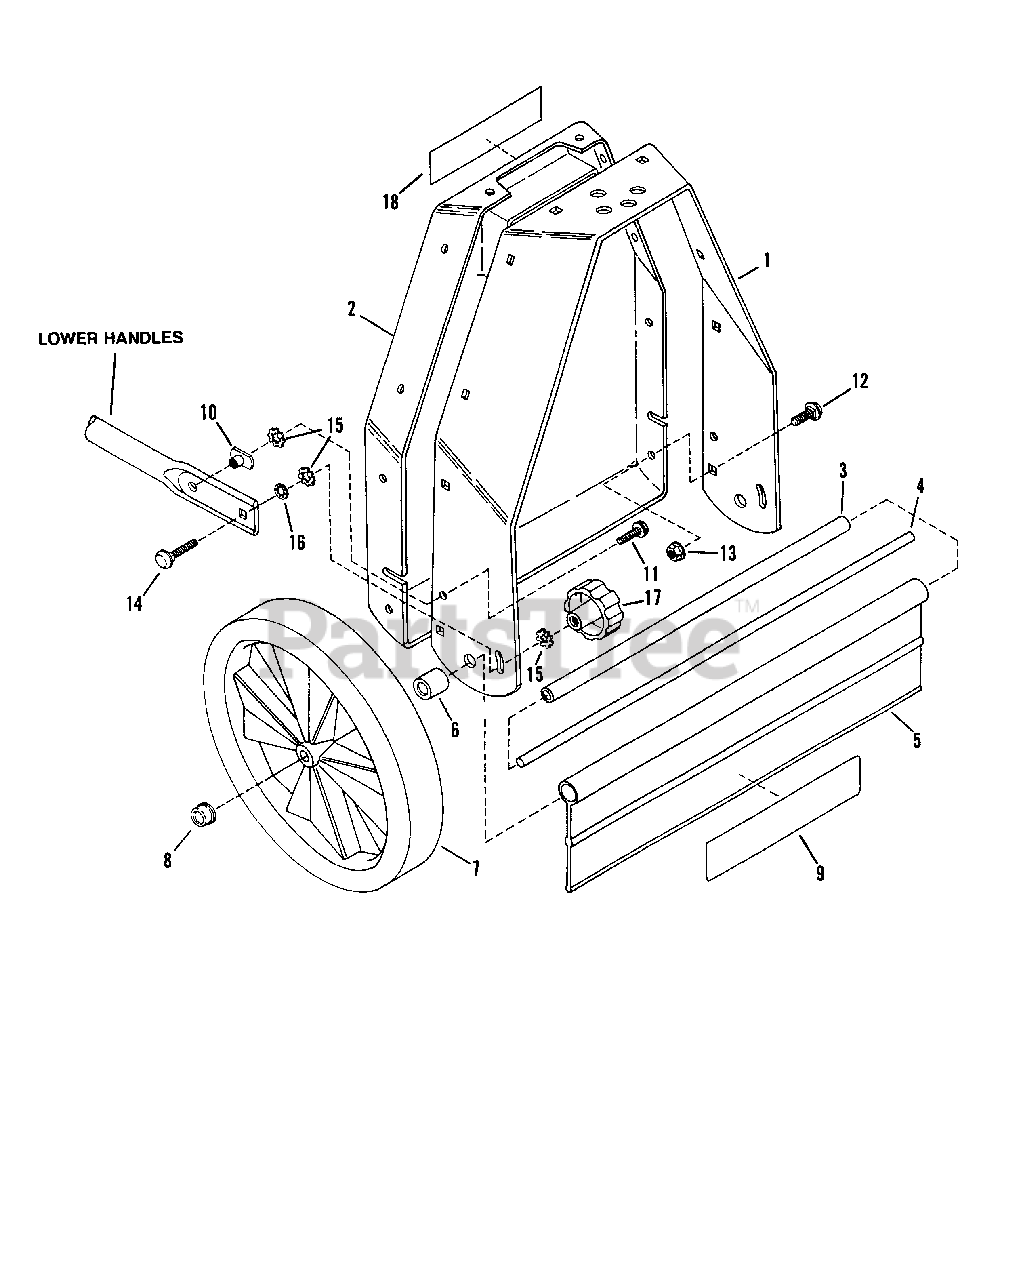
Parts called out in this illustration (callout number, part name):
1	FRAME, Main
2	PANEL, Main Frame
3	SPACER, Tube Frame
4	SHAFT, Axle
5	SHIELD, Trailing
6	BUSHING, Axle
8	NUT, 3/8 Push
9	LABEL, Trailing Shield
10	T-NUT, 5/16-18
11	BOLT, 5/16-18 x 1/2" Hex Flange Lock
12	BOLT, 1/4-20 x 1/2" Short Neck Carriage
13	NUT,1/4-20 Hex Flange Lock
14	BOLT, 5/16-18 x 3/4" Short Neck Carriage
15	WASHER, 5/16 Int./Ext. Tooth Lock
16	RETAINER, 5/16 Bolt
17	KNOB, 5/16-18 Plastic
18	LABEL, Adjustment
